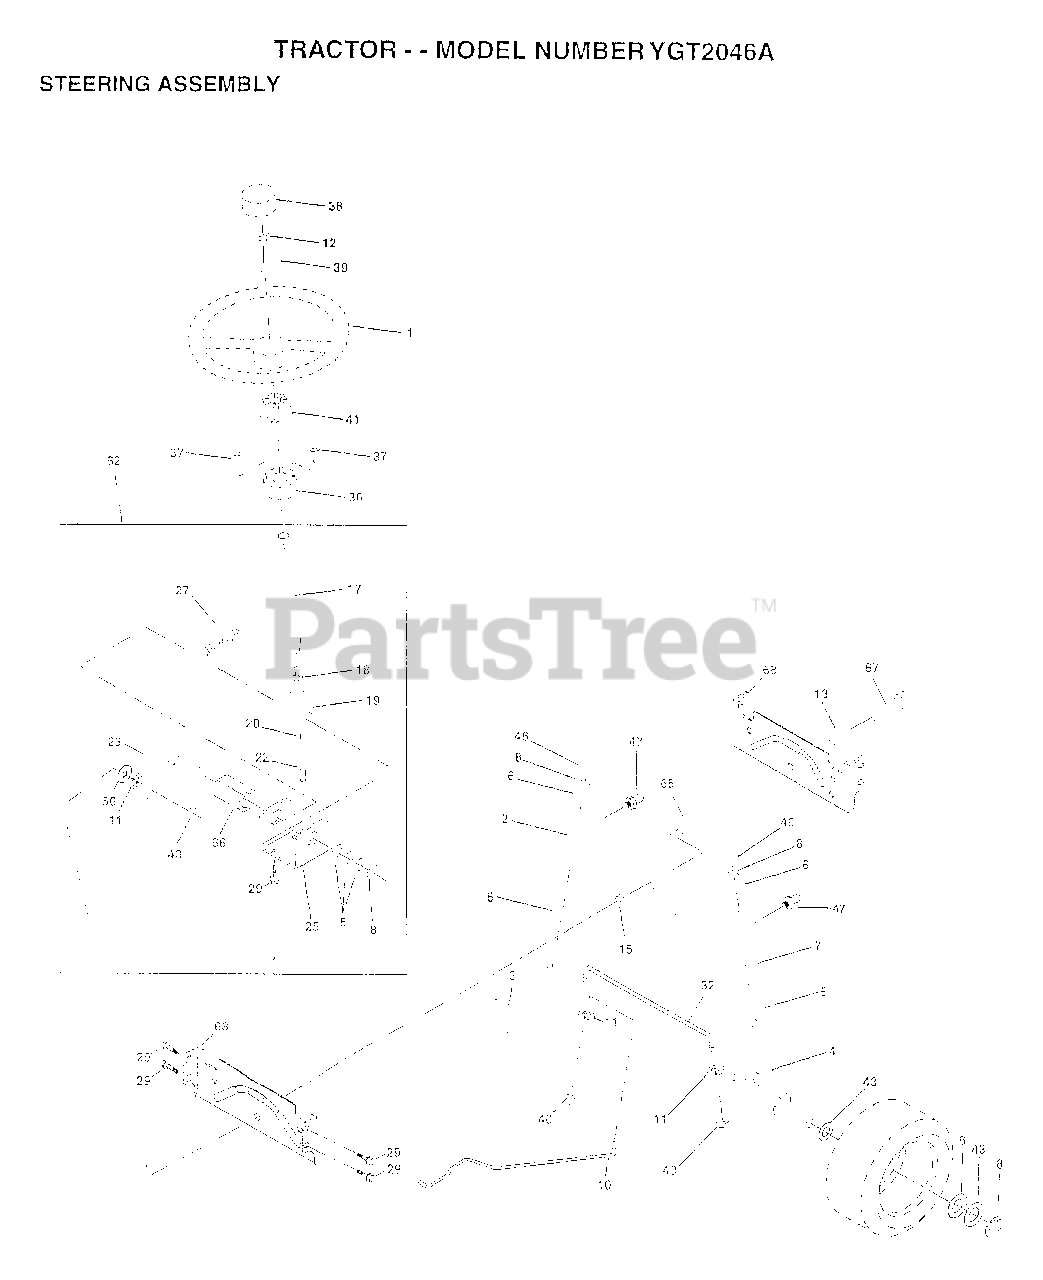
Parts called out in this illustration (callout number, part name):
3	"SPINDLE ASM,RH"
4	"SPINDLE ASM,RH"
5	WASHER .T
6	WASHER
8	RING
10	LINK.DRAG
11	LOCKWASHER
13	BEARING AXLE
15	"NUT-LOC,FLANGE LT"
17	STEERING SHAFT
18	THRUST WASHER
19	SUPPORT.SHAFT
22	SCREW HEX SOC1/4-
25	BRKT-STEERING
27	GEAR SECTOR
29	SCREW
32	ROD.ASM.TIE.BALL
36	BUSHING.STRG.3/4
37	"SCREW-TT,10-32 FL"
38	"INSERT,STR WHEEL"
39	WASHER
40	GRIPCO NUT
41	ADAPTER LT
43	WASHER
46	CAP
47	ZERK M
56	WASHER
62	STEERING KIT
65	SPACER AXLE
66	"BEARING-ARM,PITMA"
67	BOLT
68	BRACE AXLE
